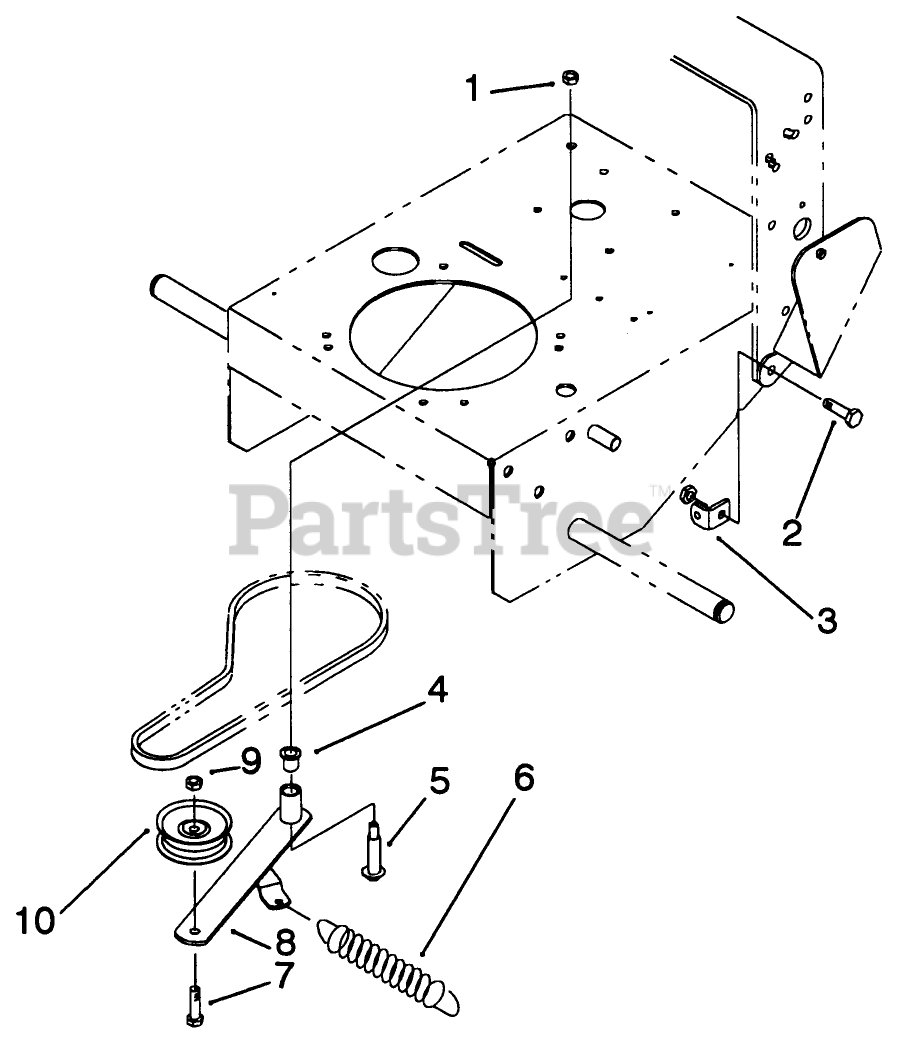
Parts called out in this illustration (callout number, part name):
1	NUT-LOCK
2	SCREW-HH
3	ANCHOR SPRING R
4	BUSHING-FLANGE
5	BOLT-WHEEL
6	SPRING
7	SCREW-HH
8	Lever-Idler
9	NUT-LOCK, NI
10	PULLEY
